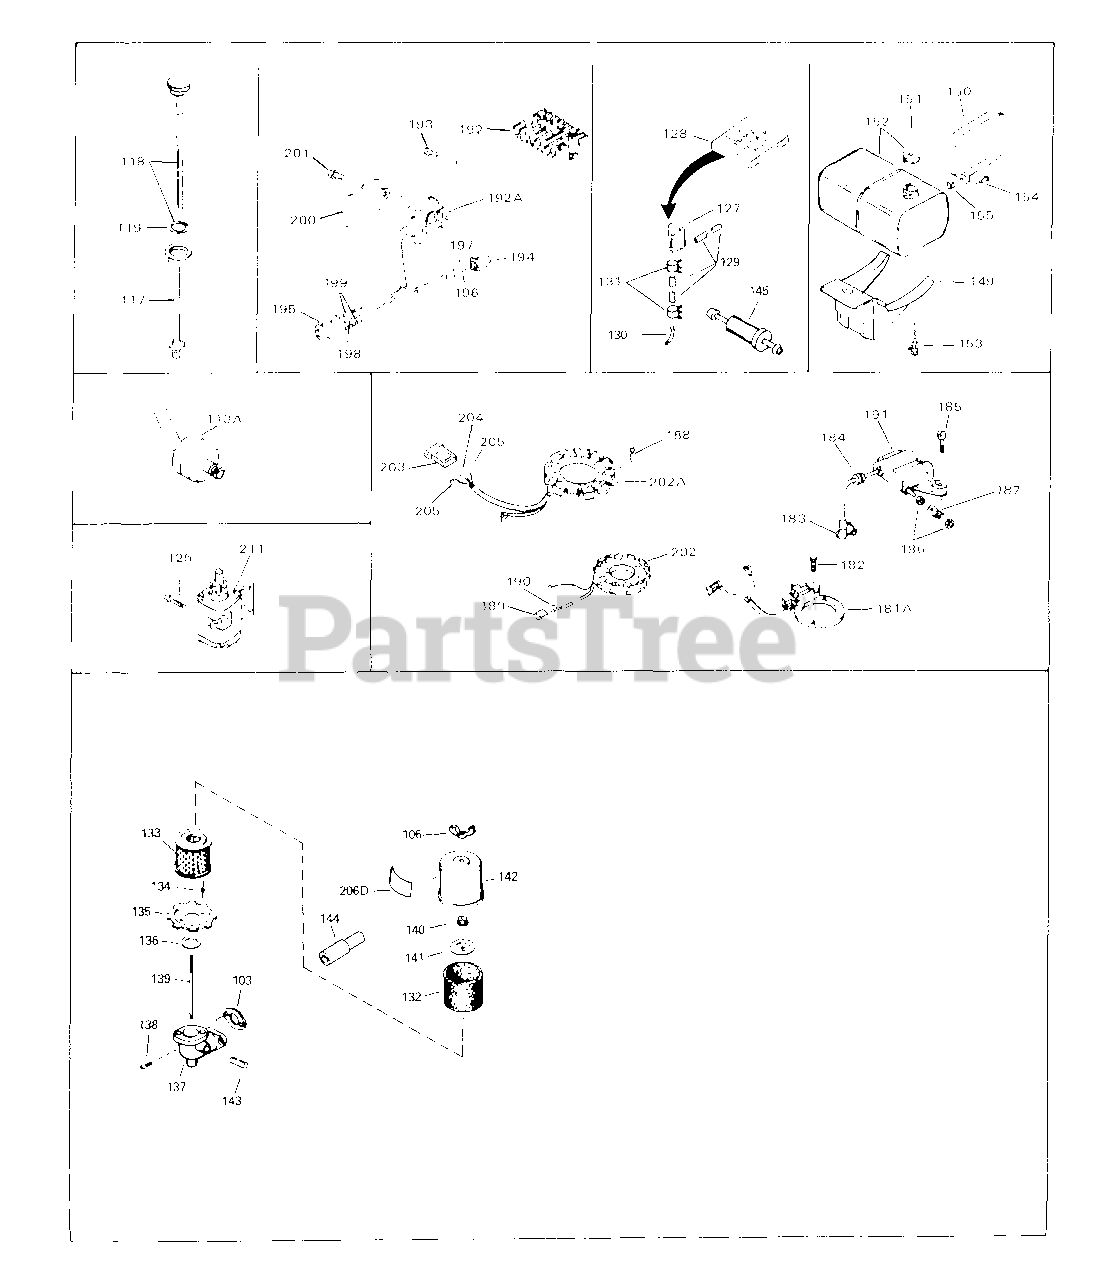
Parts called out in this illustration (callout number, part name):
103	Gasket, Air cleaner
106	Nut, Wing
117	Tube, Oil filler (Plastic)
118	Dipstick, Oil (Twist Lock)
119	"O" Ring
129	Line, Fuel (Braided) (32")
131	Clamp, Fuel line
151	Cap, Fuel filler (Red Plastic) (Spurt
183	Cover, Spark plug
184	Grommet, Lead wire
185	Screw, Fil. hd. w/conical spring wash er,
186	Nut, 8-32
187	Terminal, Female
188	Screw, Fil. hd. Sems, 10-32 x 1-1/8
191	Magneto, Solid state (Incl. Nos. 183, 184,
200	Cover plate, Blower housing
201	Screw, Pan hd., 10-16 x 3/8
202A	Coil Assy., Alternator (20 Amp)
203	Connector, Flat
204	Terminal
205	Terminal
